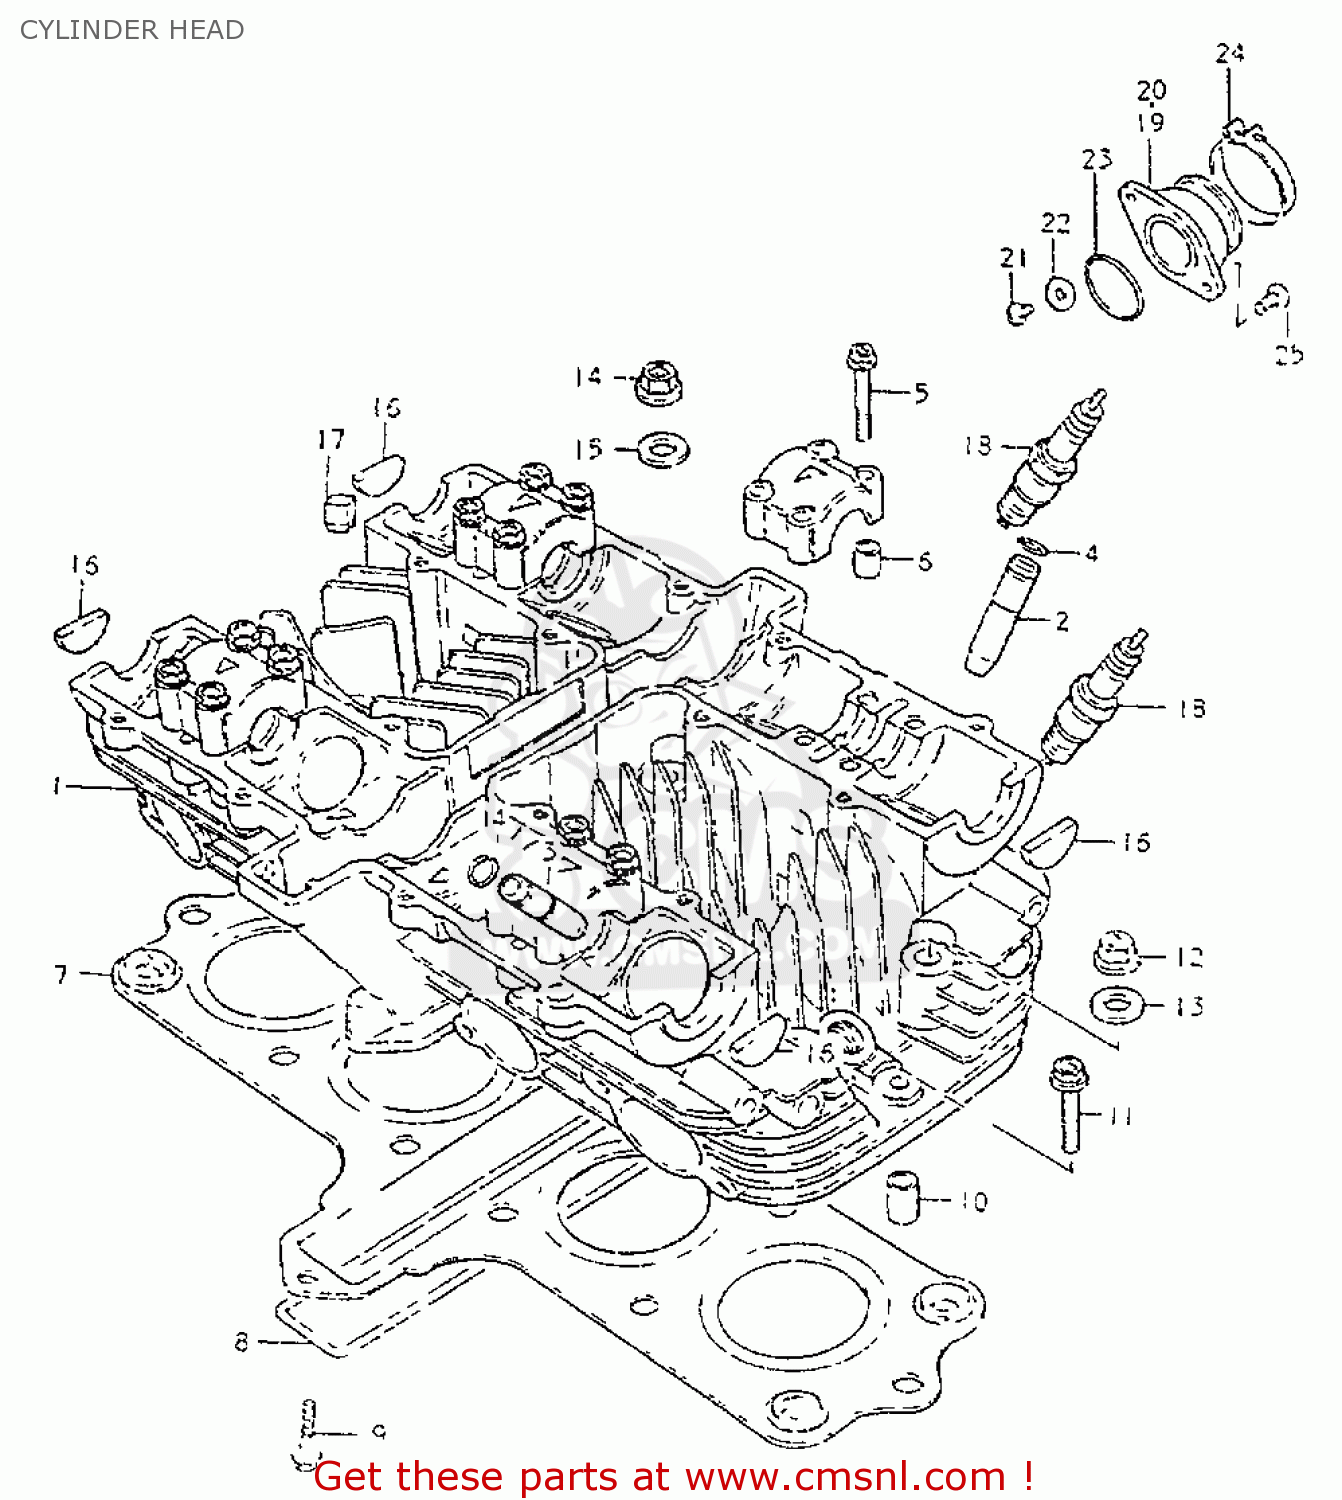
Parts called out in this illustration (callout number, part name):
1	HEAD ASSEMBLY,CYLINDER
2	GUIDE,INTAKE VALVE
3	GUIDE,EXHAUST VALVE
4	RING,SNAP
5	BOLT(6X39)
6	PIN(6.2X8X11)
7	GASKET,CYLINDER HEAD (MCA)
8	O RING(D:3,ID:26X157)
9	BOLT
10	PIN
11	BOLT,UNDER
12	NUT
13	GASKET (NAS)
14	NUT
15	WASHER(8.5X19X2.3)
16	PLUG
17	PAD
18	SPARK PLUG
19	PIPE,INTAKE,R
20	PIPE,INTAKE,L
21	BOLT
22	WASHER
23	O-RING
24	CLAMP
25	SCREW
